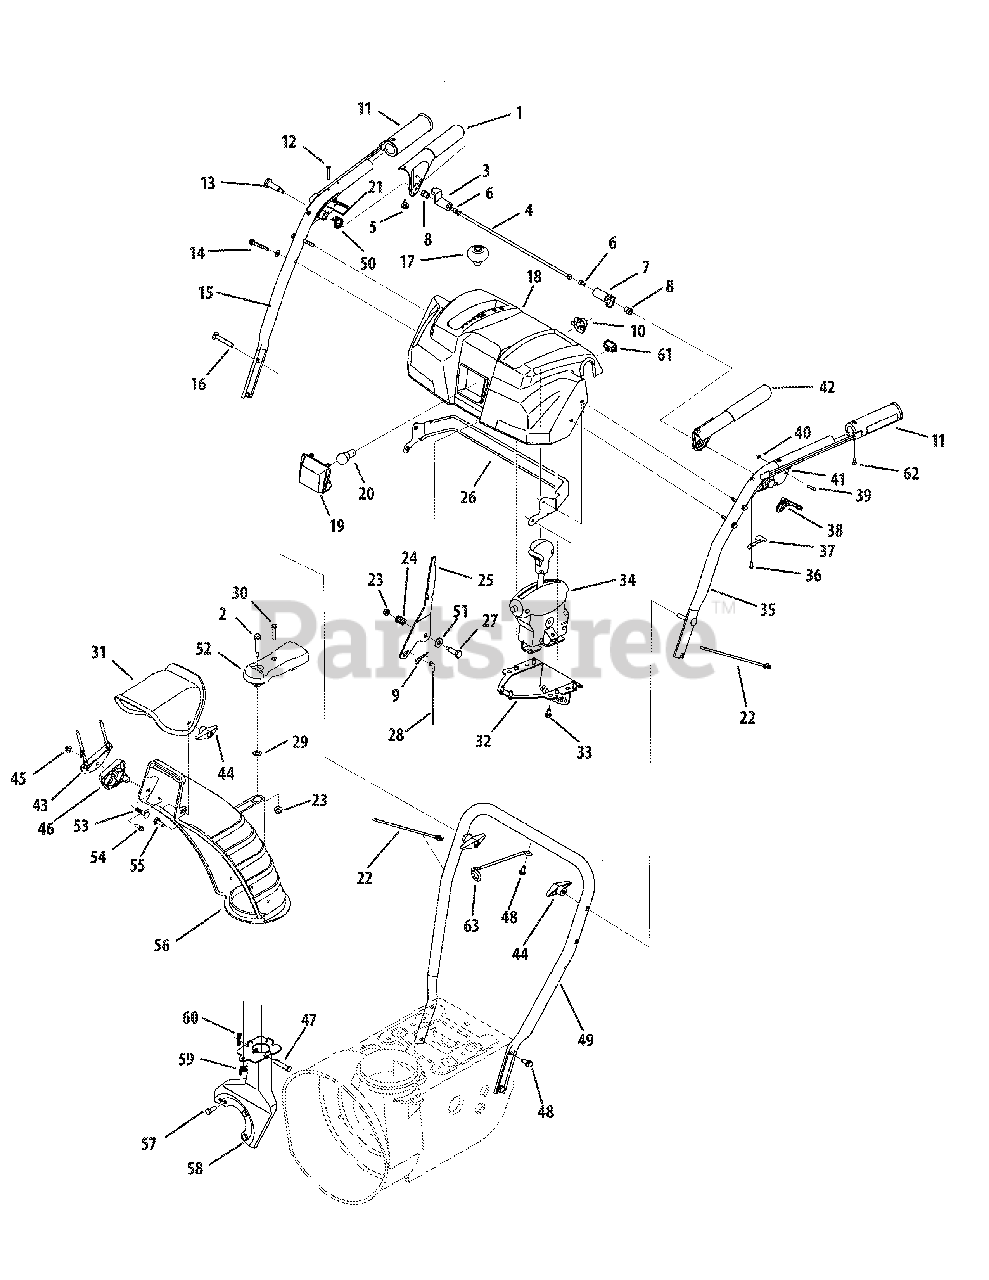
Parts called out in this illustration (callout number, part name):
1	Handle Engagement Assembly RH
2	Flange Shoulder Screw
5	Rubber Bumper
6	Socket Screw, 1/4-20 x .5
7	Clutch Lock Cam
8	Shoulder Nut, 1/4-20
9	Click Pin
10	Light Socket
11	Heated Handle Grip
12	Screw, #10-24 x 0.375
13	Shoulder Screw, 1/4-20 x .437 x 1.345
14	Screw, 1/4-20 x 1.625
16	Carriage Screw, 5/16-18 x 2.25
17	Shift Knob
18	Q-Style Handle Panel
19	Q-Style Lens
20	Lamp
21	Handle Clutch Lock - RH
22	Cable Tie
23	Flange Lock Nut, 1/4-20
24	Compression Spring
27	Shoulder Screw
28	Speed Selector Cable
29	Flat Washer, .25 x .630 x .0515
30	Screw, #10-16 x .500
31	Upper Chute
33	Hi-Lo Screw, 1/4-15 x 0.5
34	4-Way Tall Chute Control(TM) Assembly
36	Screw, #8-16 x 0.50
37	Clutch Lock Spring
38	Steering Control
41	Handle Clutch Lock - LH
42	Handle Engagement Assembly LH
44	Wing Knob
45	Flange Lock Nut, 5/16-18
46	Chute Tilt Cable Guide
50	Torsion Spring
51	Flat Washer
52	Joystick Pulley Cover
53	Carriage Bolt, 5/16-18 x 1.50
54	Hi-Lo Screw, 1/4-15 x .75
55	Carriage Bolt, 5/16-18 x 1.0
56	Lower Chute
57	Hex Screw, 5/16-24 x .750
58	Chute Support Bracket
59	Wing Nut, 1/4-20
60	Bow Tie Cotter Pin
61	Heated Grip Switch
63	Cable Guide
